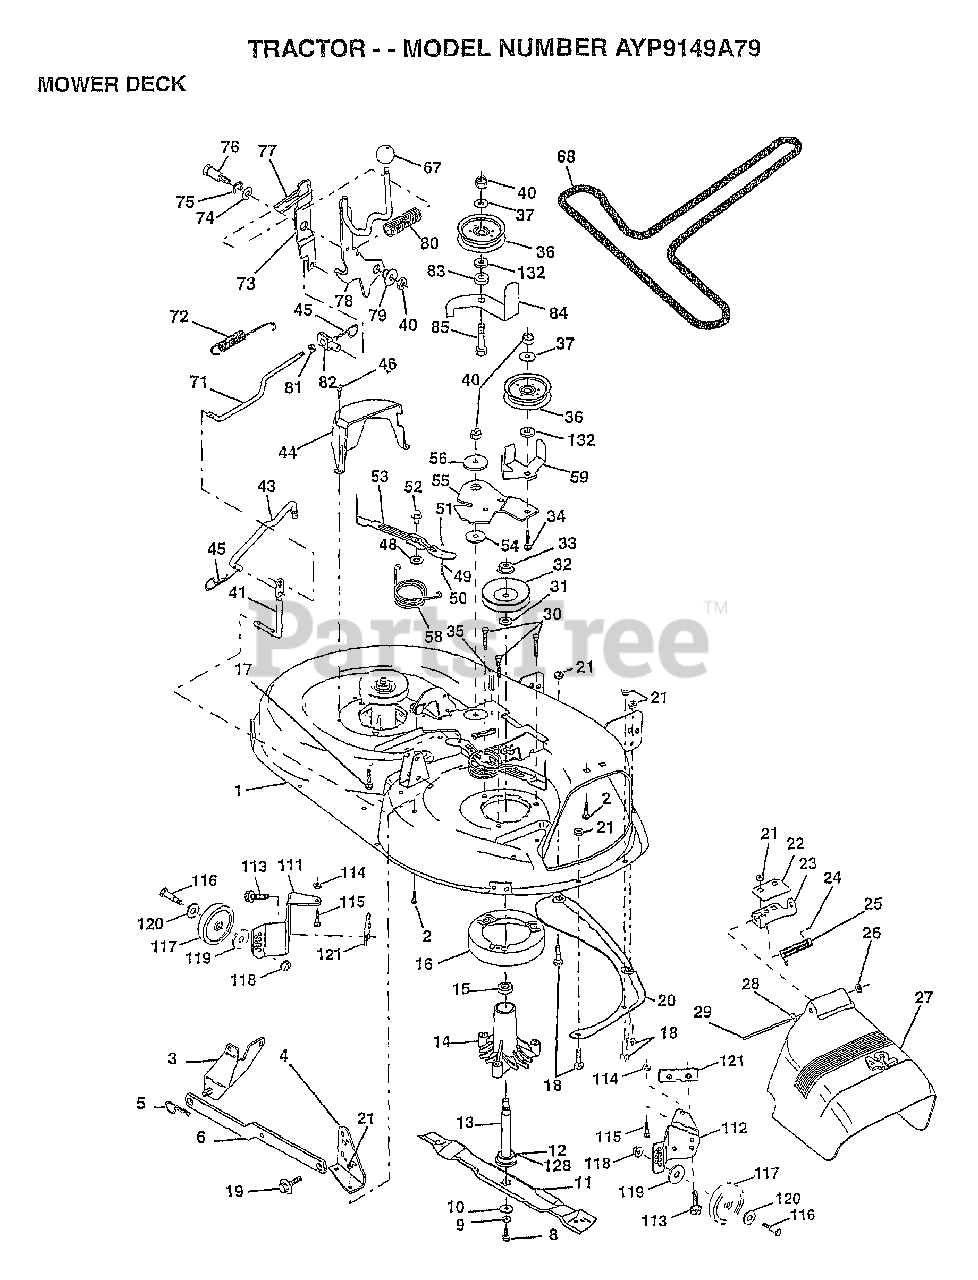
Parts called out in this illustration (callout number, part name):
1	DECK.WELD.42.
2	BOLT
3	BRKT ASM SWAY BAR
4	BRKT DECK SW BAR
8	BLADE BOLT
10	WASHER.HARD.BLADE
11	"BLADE.42"" MULCHER"
12	BEARING.BALL
14	HSG ASM MANDREL
15	BEARING
16	STRIPPER RND MWR
17	BOLT RDHD 3/8-16
18	BOLT
19	BOLT SHD 5/16-18
22	STIFFENER BRKT
23	DEFLECTOR BRKT
24	CAP-SLEEVE LT
25	SPRING TORSION
26	NUT PUSH M
27	DEFLECTOR.SHIELD
28	WASHER
29	HINGE ROD
31	WASHER
32	PULLEY.MANDREL.42
34	BOLT
35	XMAS TREE FASTNER
36	FLAT IDLER PULLEY
37	WASHER
41	PIVOT ROD
43	ROD CLUTCH W/NIBS
44	GUARD MAND LH BLK
45	RETAINER M
46	SCREW.1/4-20X5/8
48	HARD SMALL WASHER
49	ROLLER ASM-CAM
50	SHOULDER BOLT
51	LOCKNUT
52	BOLT.SHLD.5/16-18
54	HARDENED WASHER
55	ARM-IDLER
56	SPACER RETAINER
58	SPRING TORSN BRAK
59	GUARD IDLER TUV
67	KNOB T(3/8 HOLE)
68	BELT.V.T-PATH
71	ROD CLUTCH 38/42
72	RETURN SPRING
73	CLUTCH ARM SECOND
74	WASHER
75	RING
76	SHOULDER BOLT
77	SPRING KEEPER
78	LEVER ASM-CLUTCH
79	BUSHING
80	SPRING.CLUTCH.MWR
81	NUT
82	TRUNION ADJ
83	WASHER
84	"KEEPER-BELT,FIXED"
85	BOLT RDHD 3/8-16
92	NUT
111	BRACKET GUAGE WHEEL LH 42" DECK
112	BRACKET.GWHL.RH.
113	SCREW
116	BOLT M
117	WHEEL.GAGE.BLK.PL
118	LOCKNUT
119	WASHER
120	WASHER
121	BRACKET.EXTRD.GWL
128	WASHER.FELT.
132	WASHER GT
